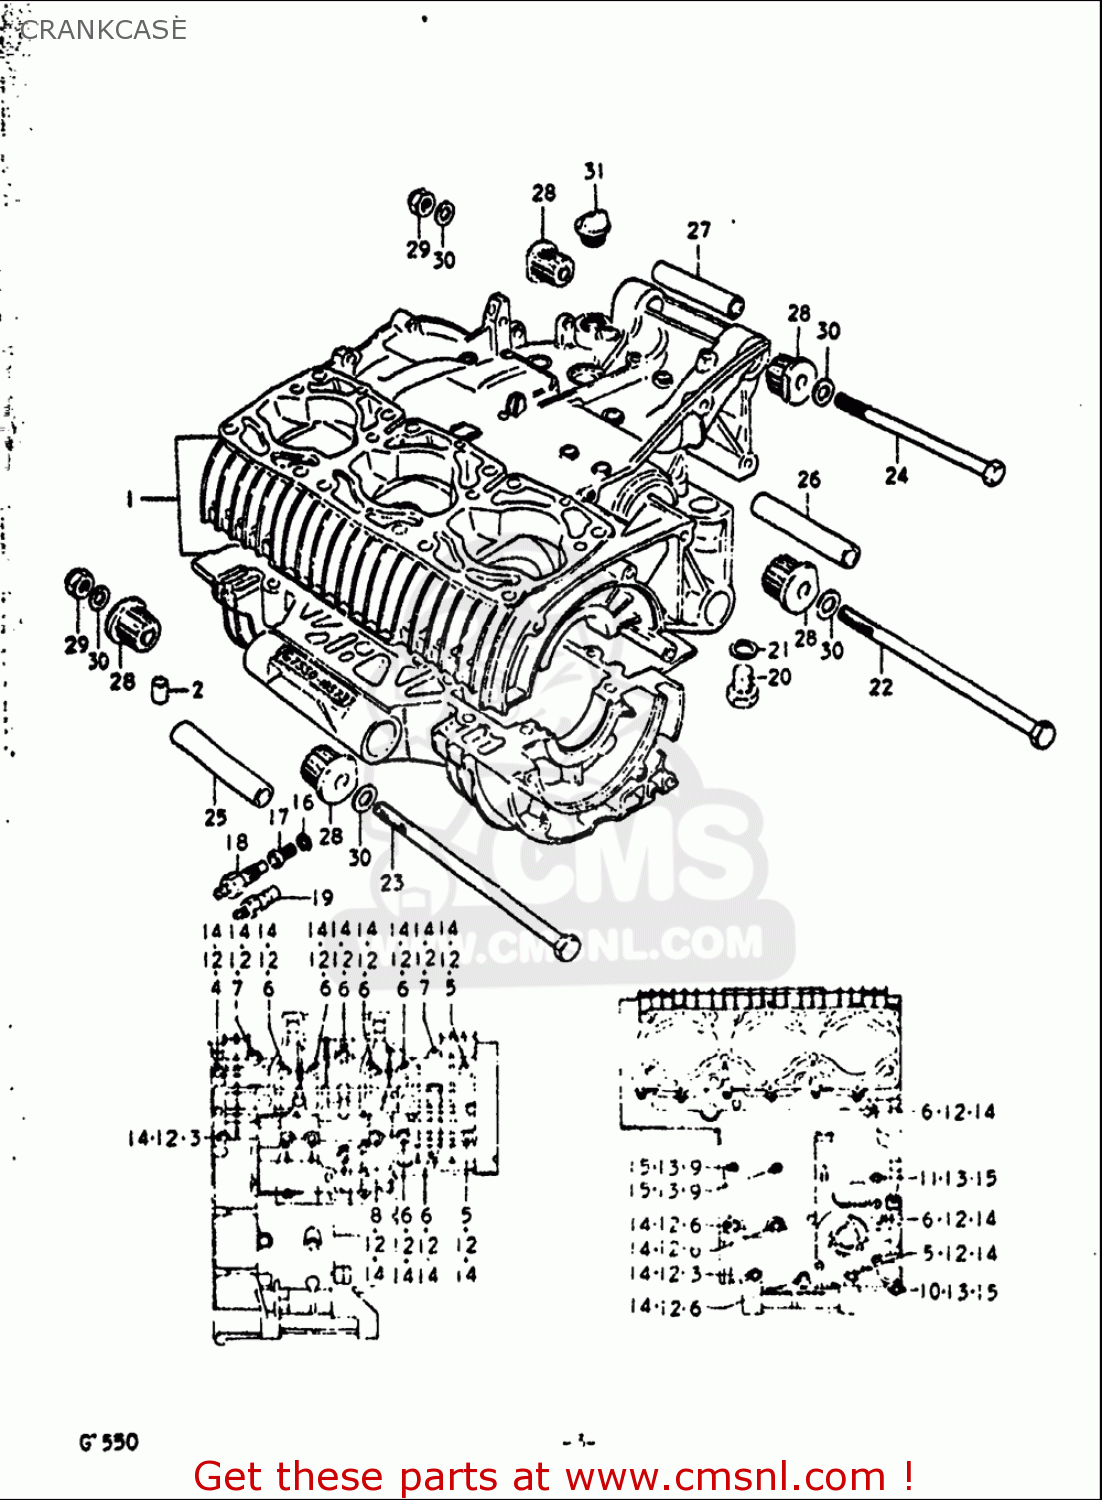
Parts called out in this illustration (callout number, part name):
2	PIN
3	BOLT(8X105)
4	BOLT
5	BOLT
6	BOLT
7	BOLT
8	BOLT
9	BOLT
10	BOLT
11	BOLT
12	WASHER
13	WASHER
14	WASHER,LOCK
15	WASHER,LOCK
16	GASKET(8.2X14X1) (NAS)
18	CHECK VALVE,SRIS
20	PLUG
21	GASKET(14X19.2X2) (NAS)
24	BOLT(10X185)
28	BUSH
29	NUT
30	WASHER
31	PLUG SET
